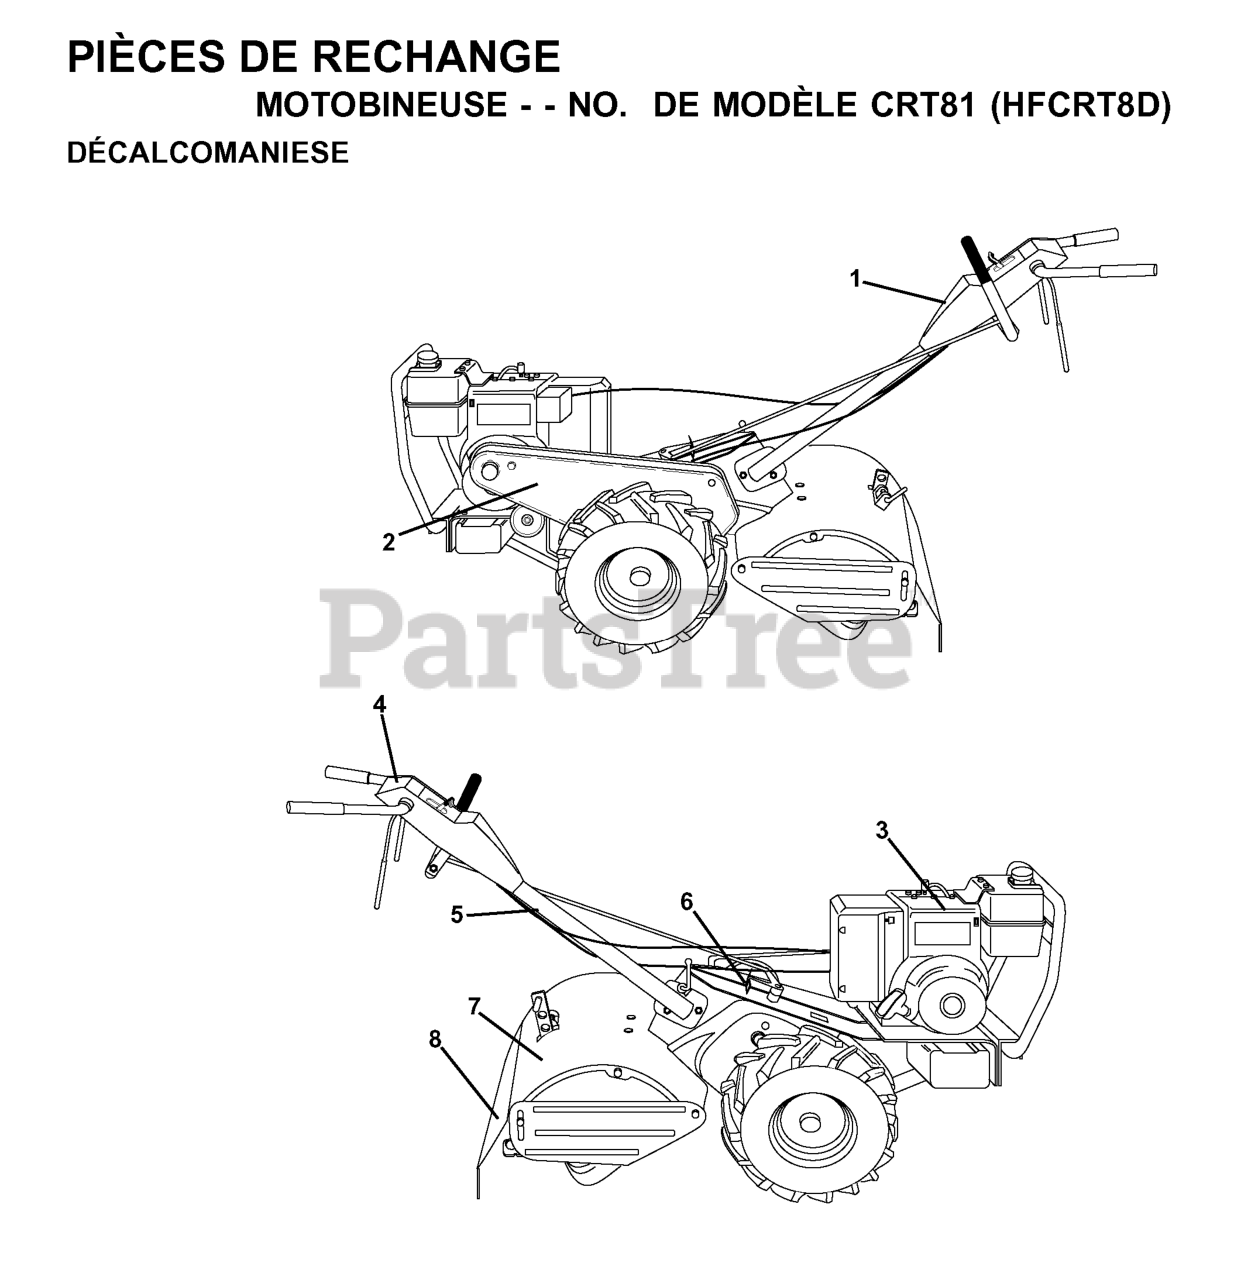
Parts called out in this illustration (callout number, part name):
1	DECAL, LOGO
3	DECAL EUROPE STANDARD CE
4	DECAL INSTRUCTION
5	DECAL.PLACEMENT.HAND.SYMBOLS
6	DECAL, SHIFT INDICATOR
